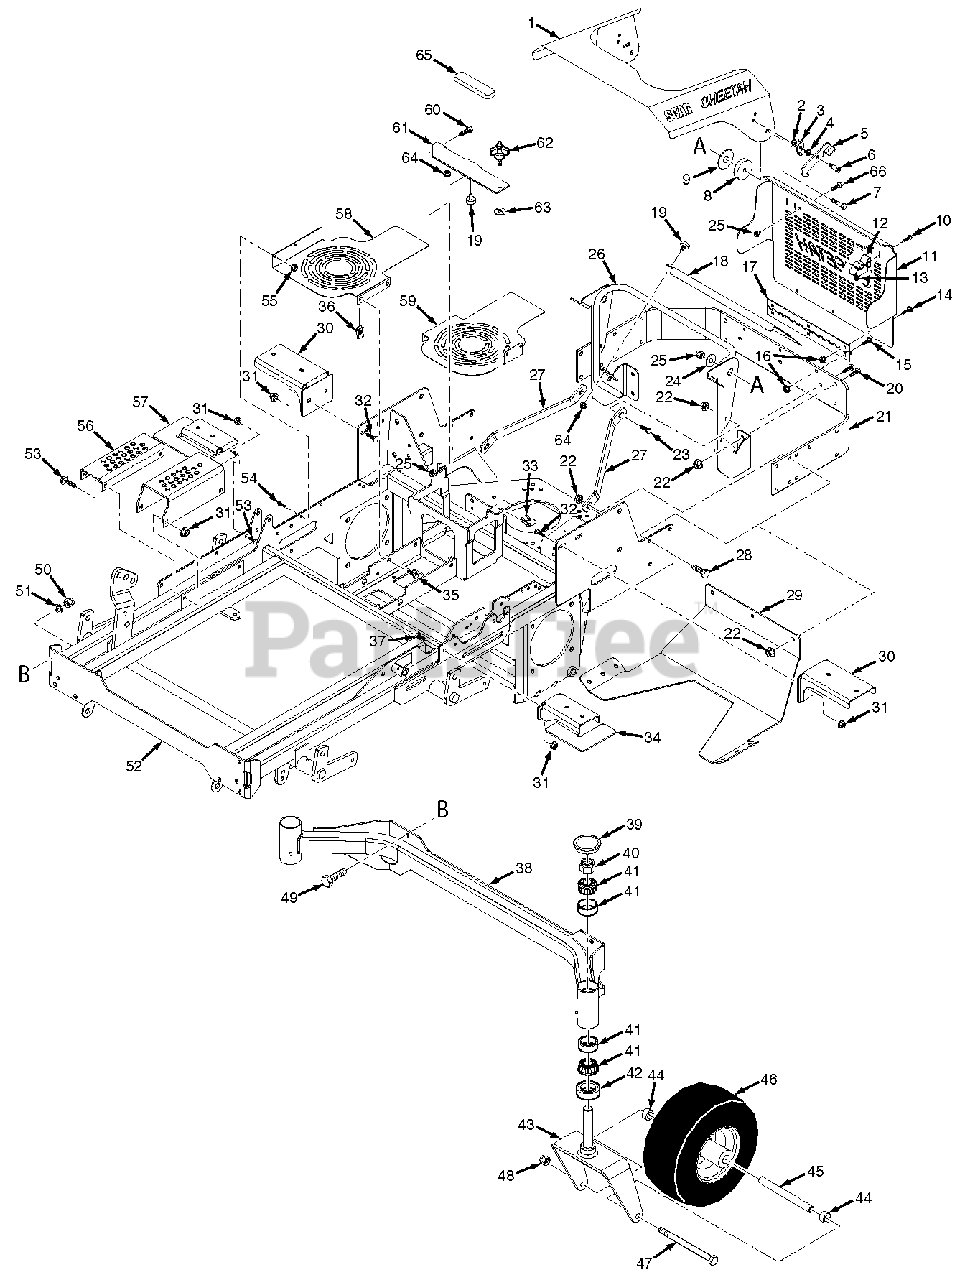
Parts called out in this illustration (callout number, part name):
1	ROPS, Foldable SCZ
2	Pin Assembly
3	Spring, ROPS
4	Clip, ROPS
5	Bolt, Hex Head 1/2-13 x 3-1/4"
6	Nut, Elastic Stop 1/2-13
7	Spring Clip, ROPS
8	Nut, Center Lock 1/2-13
9	Flatwasher, 1/2-.562 x 1.375 x .109
10	ROPS Mount, RH Rear
11	ROPS Mount, LH Rear
12	Bolt, Hex Head 1/2-13 x 1-1/4"
13	Bolt, Hex Head 1/2-13 x 4-1/4"
14	Seat Belt Kit, Retractable - SCZ
